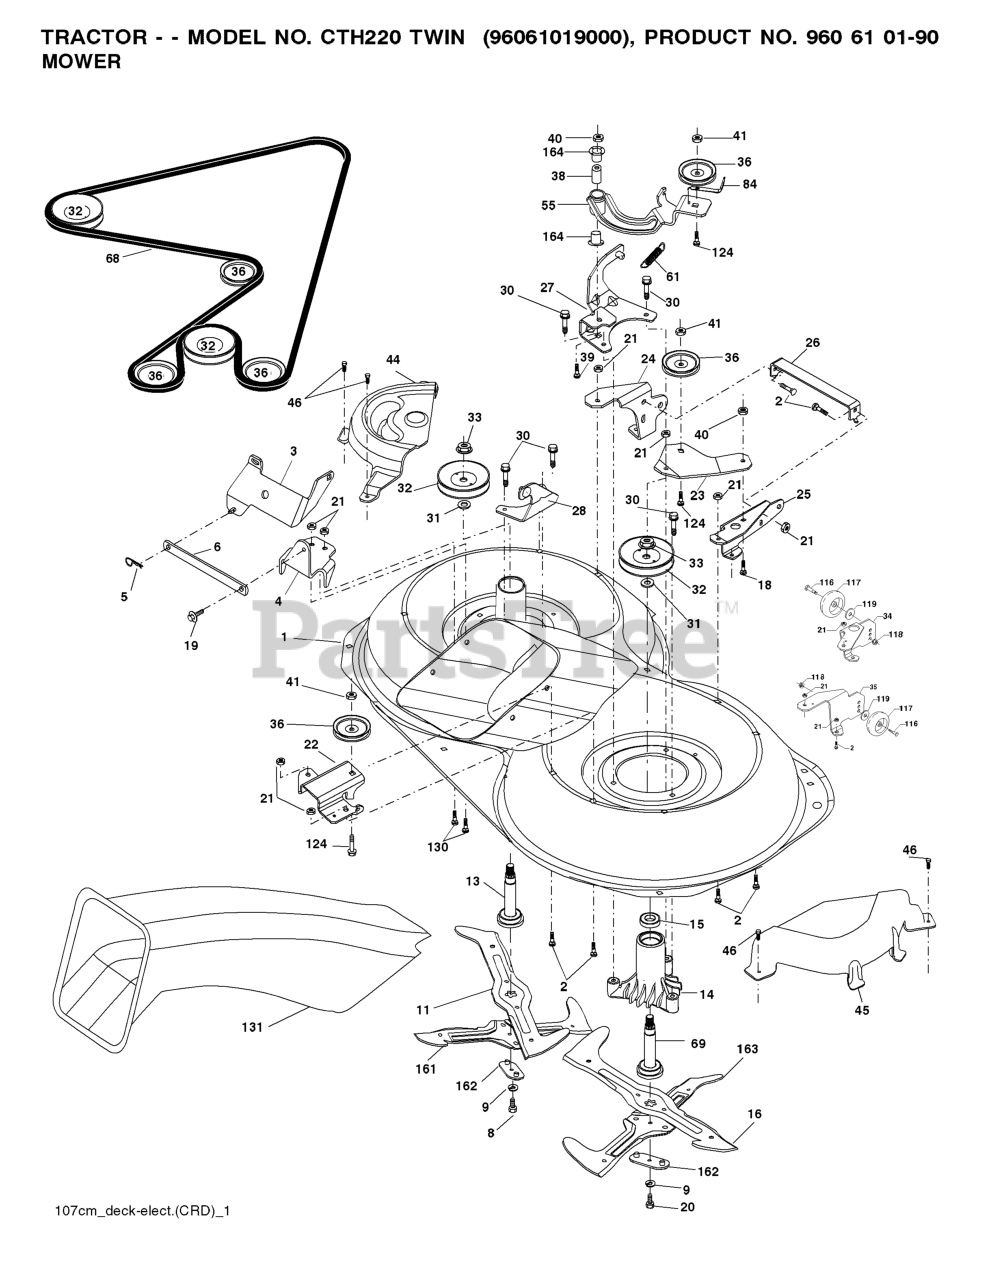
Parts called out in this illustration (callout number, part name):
1	Housing Asm. Mower 107 CRD
2	RP BOLT 5/16-18 X3/4 ZN/YEL GR
5	RETAINER-SPRNG RB
6	BAR.SWAY.92.CRD
8	BOLT.3/8-24X1.25 GR8
9	LOCKWASHER
11	BLADE.3N1.LH.CRD
13	SHAFT ASM VENT
14	HOUSING.MANDREL.VENTED (MACHD)
16	BLADE.3N1.RH.CRD
19	BOLT SHD 5/16-18
20	BOLT.3/8-24X1.25GR8. LHTHRD
21	LOCKNUT
22	BRACKET.IDLER.RR.107.CRD
25	BRACKET RF
26	SUPPORT
28	BRACKET
30	SCREW, WASHER HEAD
31	WASHER.SPACER.MANDREL
32	PULLEY.MANDREL.4.80 PD.2006
33	NUT.FLANGE.LOCK.TOP
34	BRACKET
35	BRACKET
36	PULLEY.IDLER.4.25
41	NUT LOCK FLG 3/8-16 UNC
45	COVER.MANDREL.RH.CRD
46	SCREW.1/4-20X5/8
55	ARM.IDLER.107.CRD
61	SPRING
68	HEX-BELT 107 MOWER
69	SHAFT.ASM.W/LWR.BRG.RH.THREAD
84	KEEPER, BELT IDLER
116	BOLT.SHOULDER.3/8-16X3-5/8.
117	RP WHEEL. GUAGE RALLY
118	NUT LOCK FLG 3/8-16 UNC
119	WASHER
124	BOLT.3/8-16X1.50
130	BOLT.CARR.SQNK.5/16-18UNC.X3/4
131	CHUTE BAGGER
163	BLADE.CROSS.RH.CRD.107
164	BRNG T
